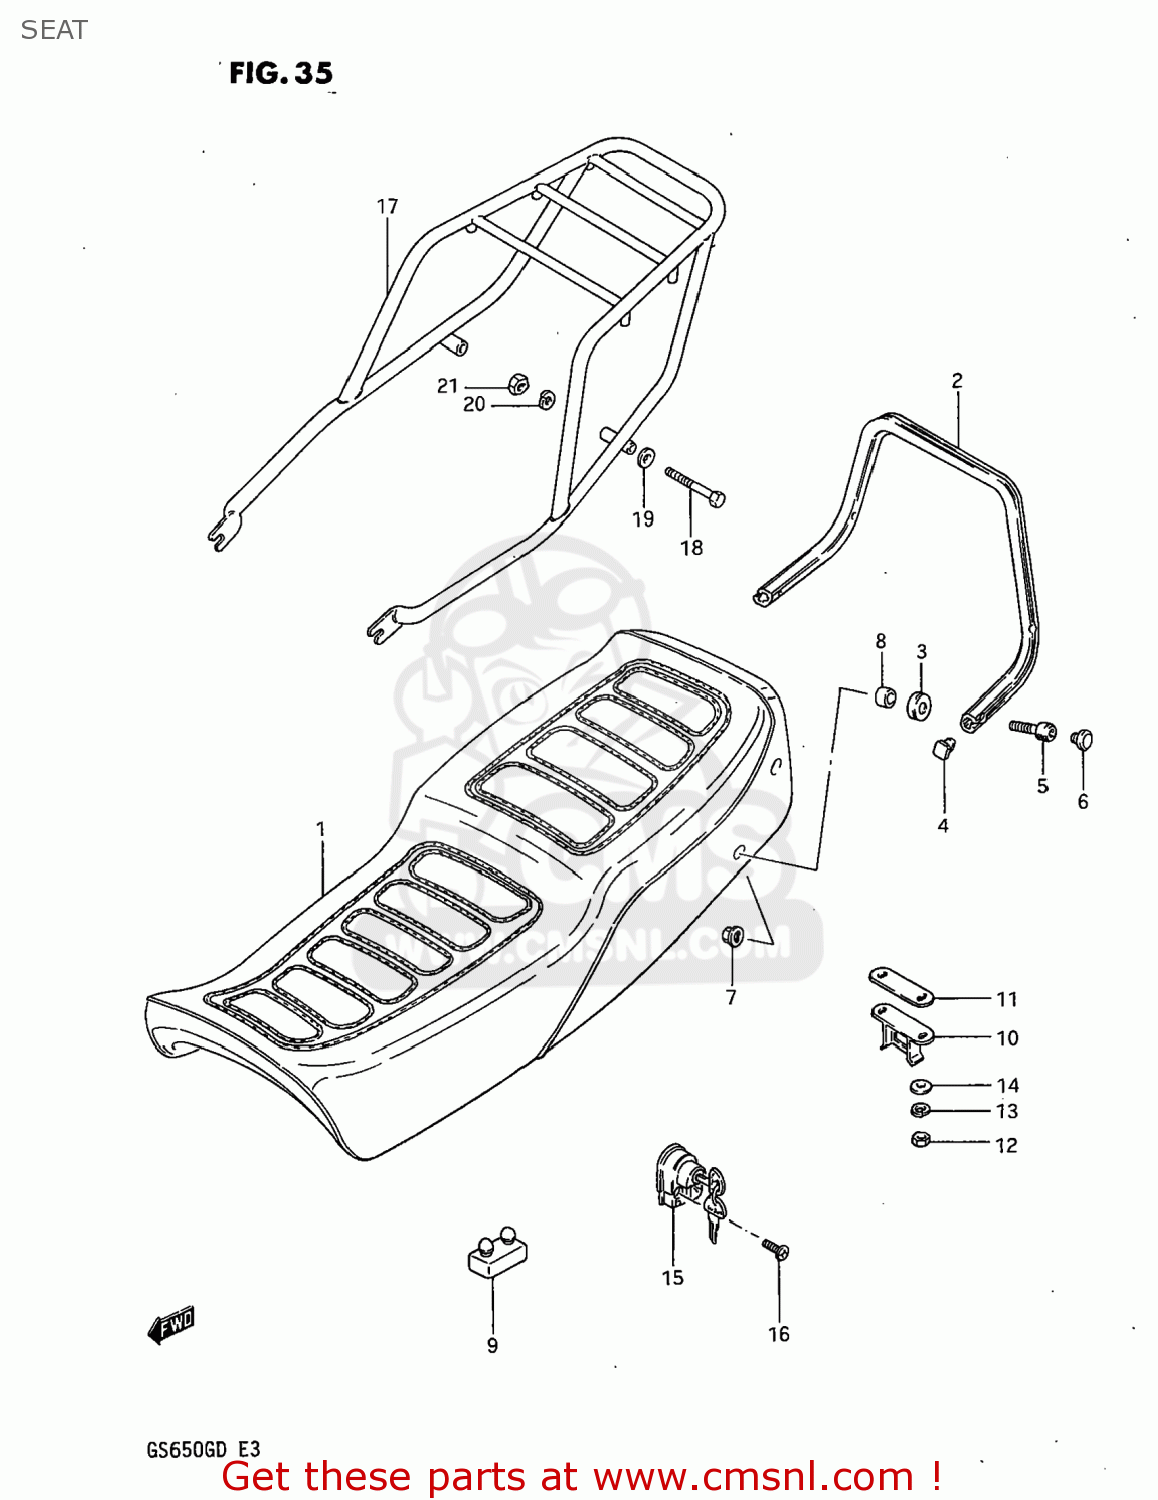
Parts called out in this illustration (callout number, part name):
1	SEAT ASSEMBLY
2	HANDLE,PILLION RIDER
3	CUSHION
4	HANDLE,PILLION RIDER
5	BOLT
6	CAP(OD:14.5)
7	NUT
8	SPACER,REAR
9	CUSHION
10	STRIKER,SEAT LOCK
11	SHIM,SEAT LOCK STRIKER
12	NUT 6MM
13	LOCK WASHER
14	WASHER
15	LOCK ASSY,HELMET
16	BOLT 5X25
17	CARRIER
18	BOLT
19	WASHER
20	LOCK WASHER
21	NUT 8MM
